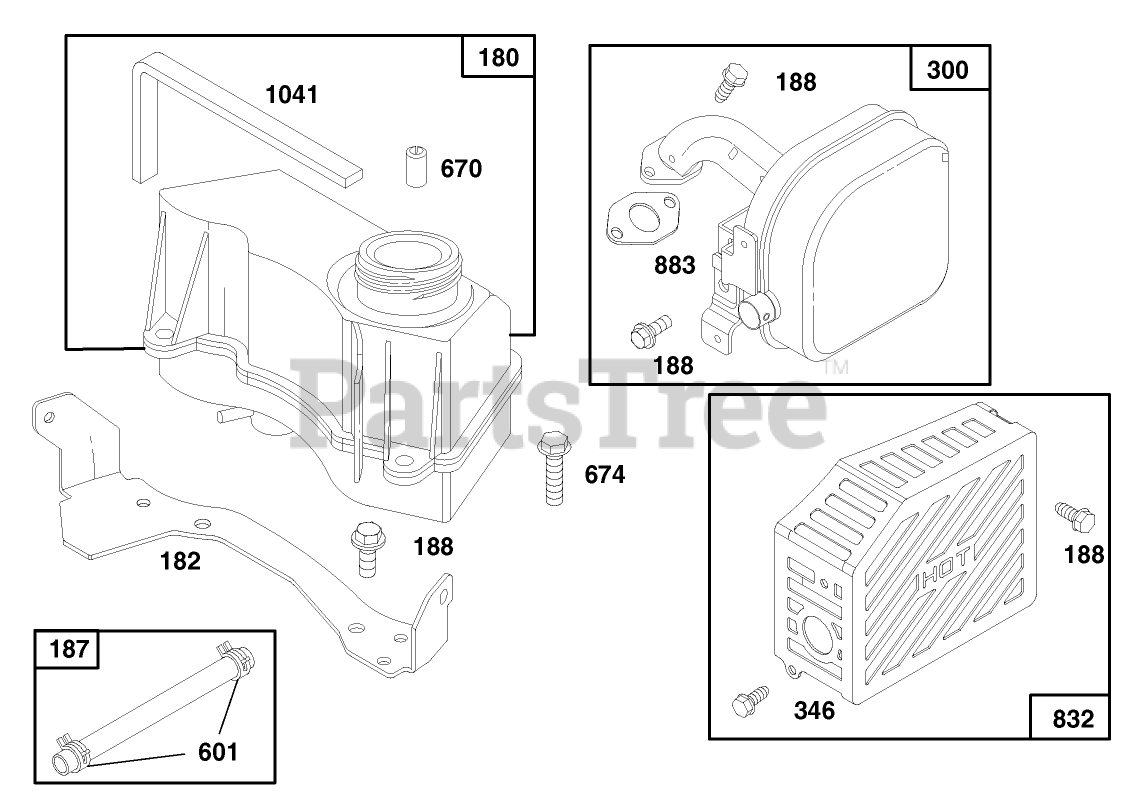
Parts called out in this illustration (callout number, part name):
180	TANK ASSY - FUEL
187	BRIGGS 296004
300	MUFFLER - EXHAUST
670	SPACER
674	SCREW - HEX HEAD
